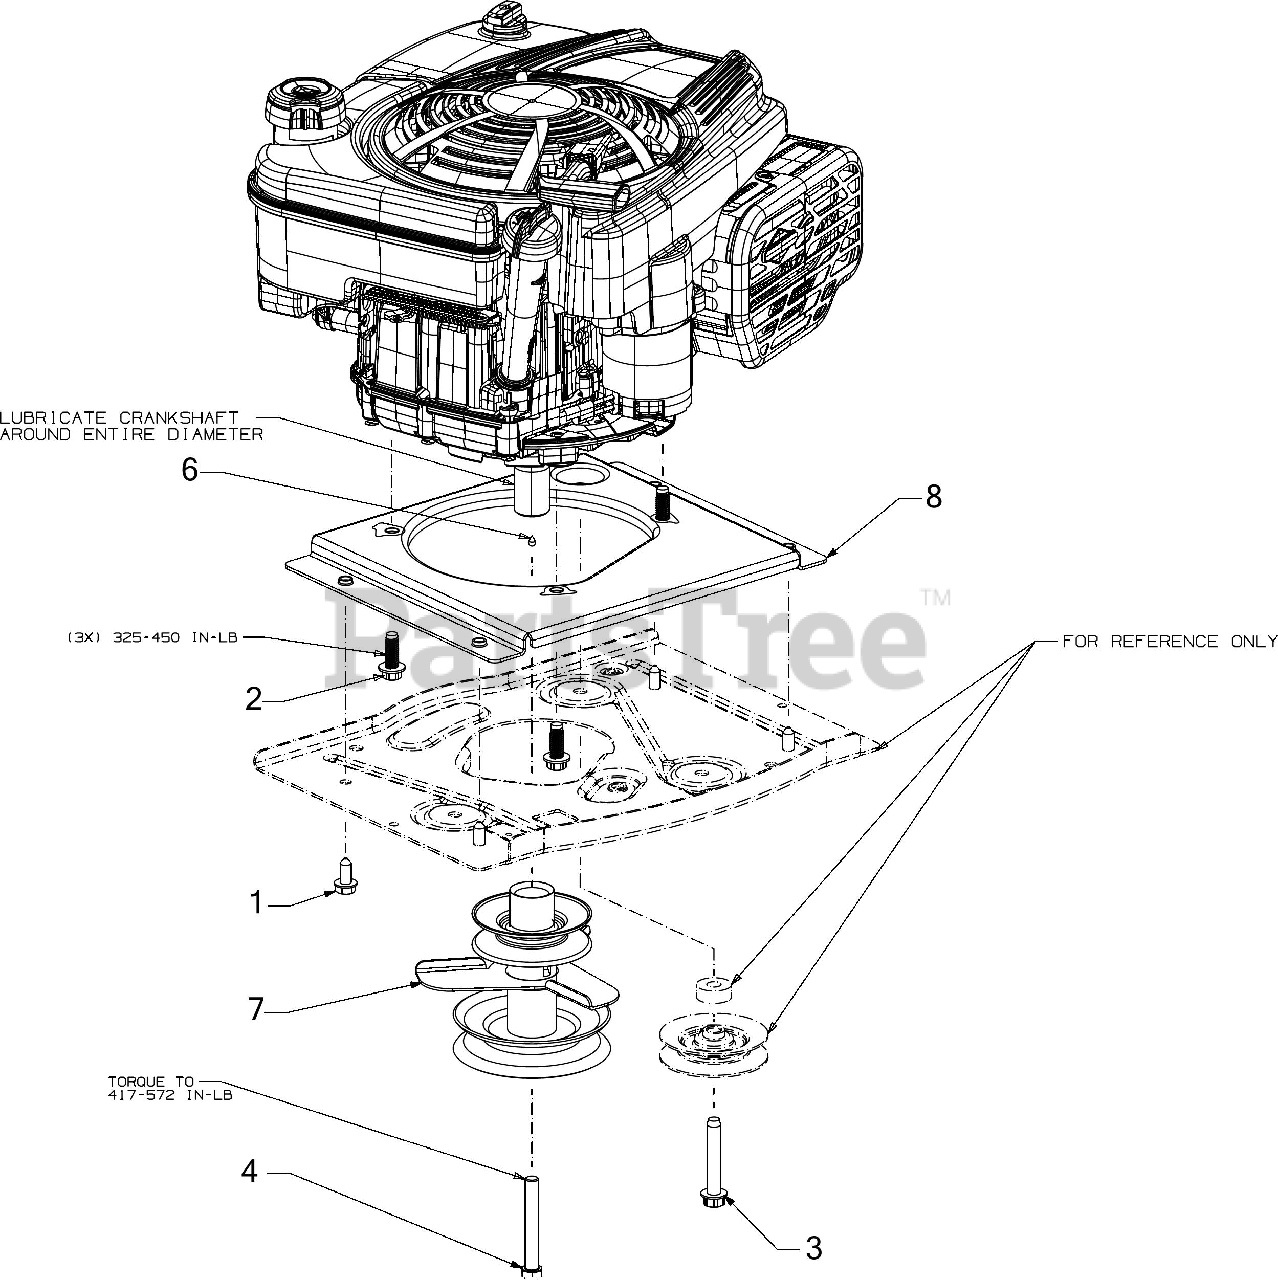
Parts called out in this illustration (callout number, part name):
1	SCREW 5/16-18 x .750
2	SCREW 3/8-16 x 1
3	SCREW 3/8-16 x 2.250
4	SCREW 3/8-24 x 2.75 GR5
6	ANTI-SIEZE GREASE
7	PULLEY-4.46 DIA/3.39 DIA
8	ENGINE PLATE MOUNT
